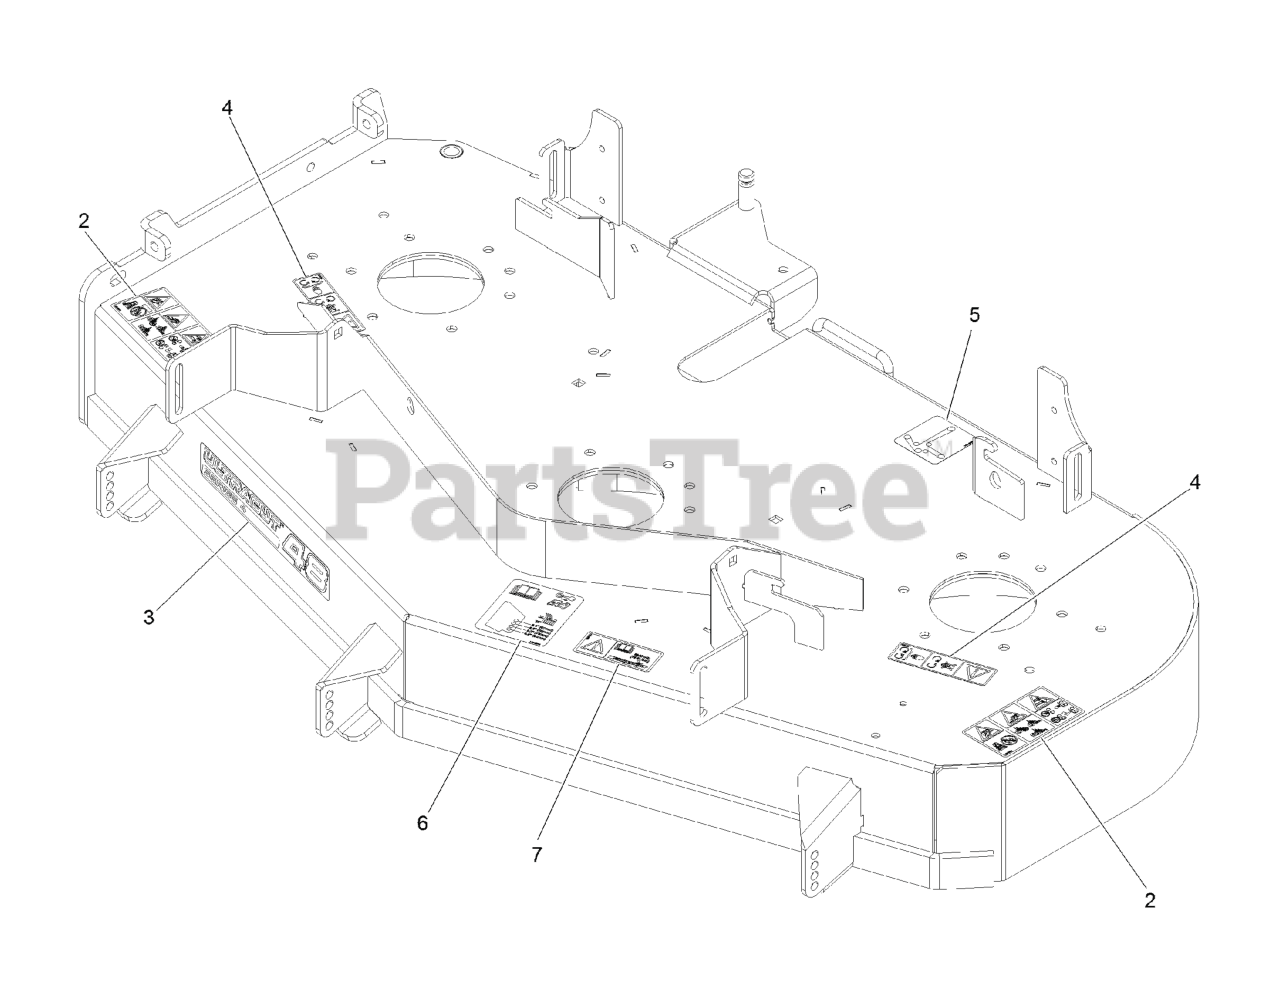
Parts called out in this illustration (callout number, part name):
2	DECAL-DANGER THROWN OBJECTS
3	Decal, 484
4	DECAL-COVER, MISSING
5	DECAL-ROUTING, BELT
6	DECAL-ROLLER, ANTI-SCALP
7	DECAL-BOLT TORQUE
